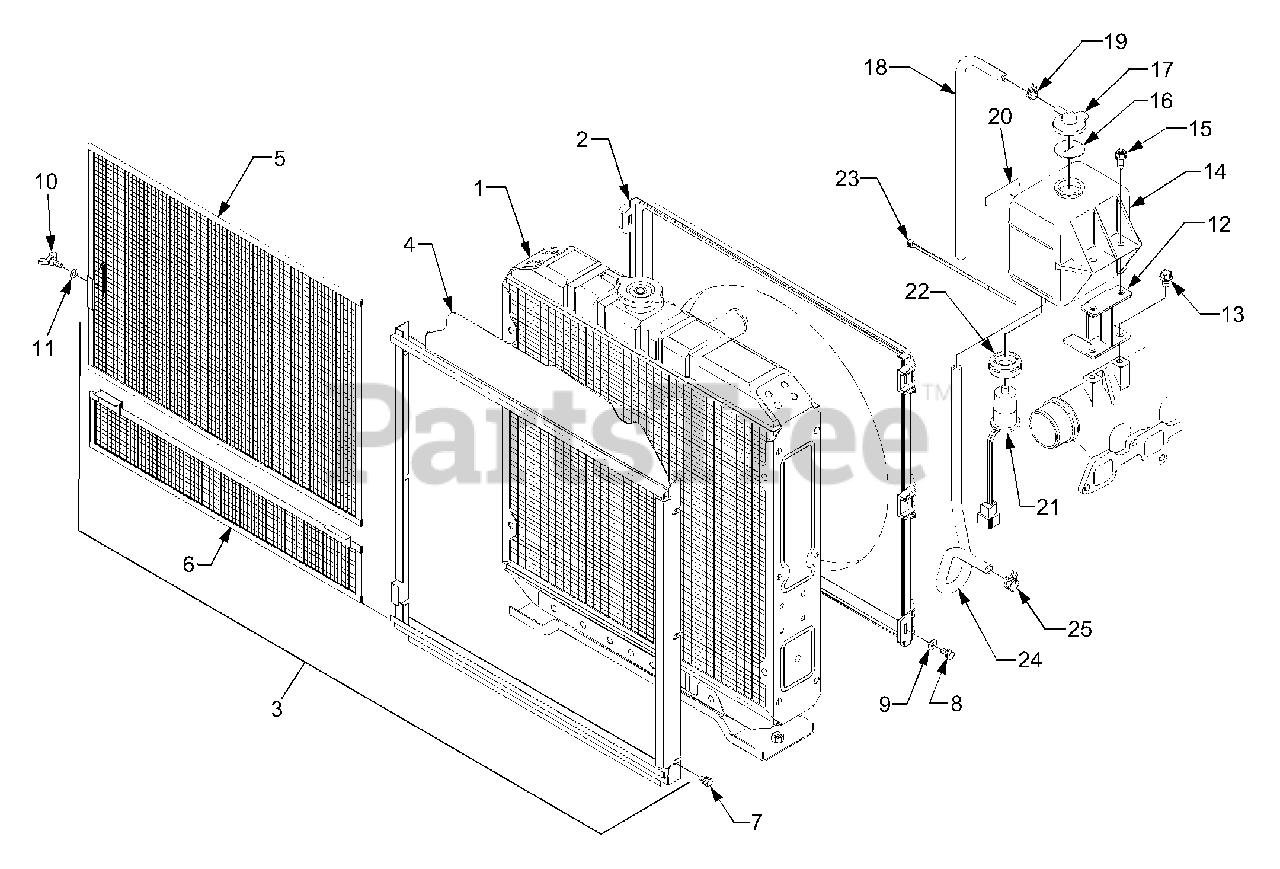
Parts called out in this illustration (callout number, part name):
1	Radiator Ass'y
3	Screen/Guide Ass'y
4	Guide, Screen
5	Screen, Radiator
6	Screen, Radiator
9	Washer, Plain
11	Washer, Plain
12	Stay, Reserve Tank
14	Reserve Tank Ass'y
16	Plate, Rubber
18	Pipe, Water Over Flow
21	Switch, Water Level
22	Rubber, Holder
24	Pipe,water Over Flow
